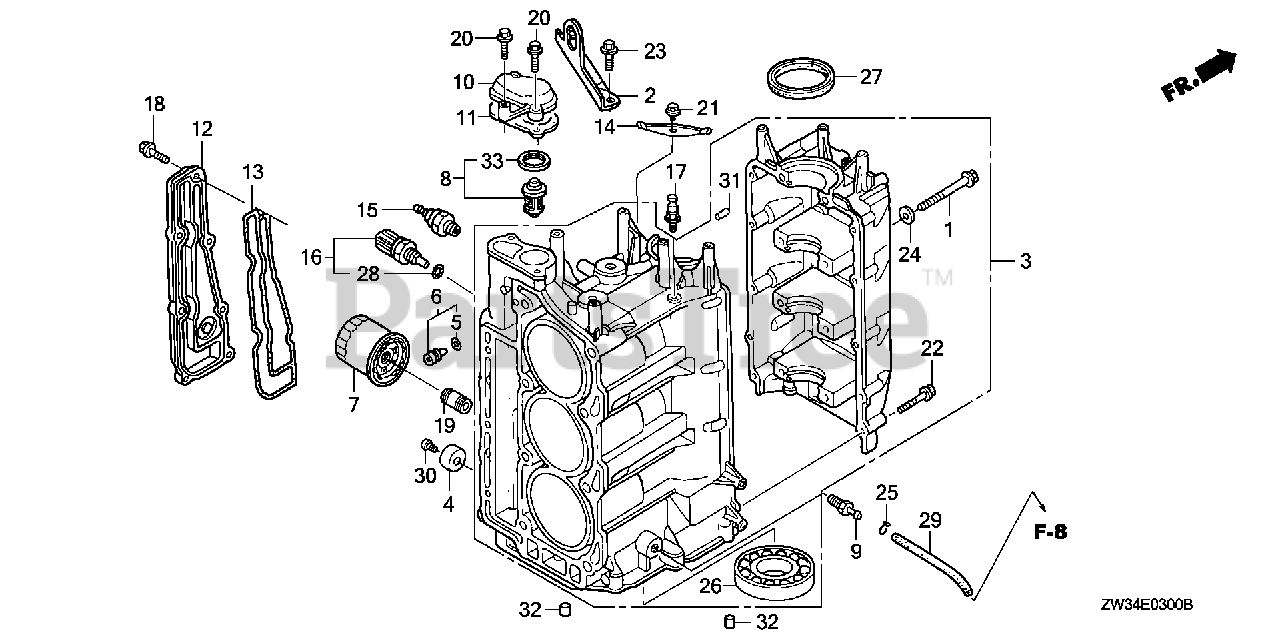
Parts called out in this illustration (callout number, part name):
1	BOLT, FLANGE (8X94)
2	HANGER, ENGINE
3	BLOCK ASSY., CYLINDER *NH8* (DARK GRAY)
4	METAL, ANODE
5	O-RING (4.8X1.9)
6	ORIFICE ASSY., OIL PASSAGE
7	FILTER, OIL (DENSO)
7	FILTER, OIL (TOYO ROKI)
8	THERMOSTAT ASSY.
9	JOINT, WATER TUBE
10	COVER, THERMOSTAT
11	GASKET, THERMOSTAT COVER
12	COVER, WATER JACKET
13	GASKET, WATER JACKET COVER
14	HOLDER, WIRE (A)
15	SWITCH ASSY., OIL PRESSURE
16	SENSOR ASSY., WATER TEMPERATURE
17	BOLT, TIMING BELT ADJUSTING SPRING
18	BOLT, FLANGE (6X22) (CT200)
19	HOLDER, OIL FILTER
20	BOLT, FLANGE (6X20)
21	BOLT, FLANGE (6X12)
22	BOLT, FLANGE (6X40)
23	BOLT, FLANGE (8X18)
24	WASHER, PLAIN (8MM)
25	CLIP, TUBE (B10)
26	BEARING, RADIAL BALL (6005)
27	OIL SEAL (56X70X8)
28	O-RING (9.5X1.5) (HONDA KIKAKI)
29	TUBE, WATER CHECK
30	SCREW, PAN (6X18)
31	PIN, DOWEL (10X12)
32	PIN A, DOWEL (12X16)
32	PIN, DOWEL (6X10)
33	RUBBER, RING
